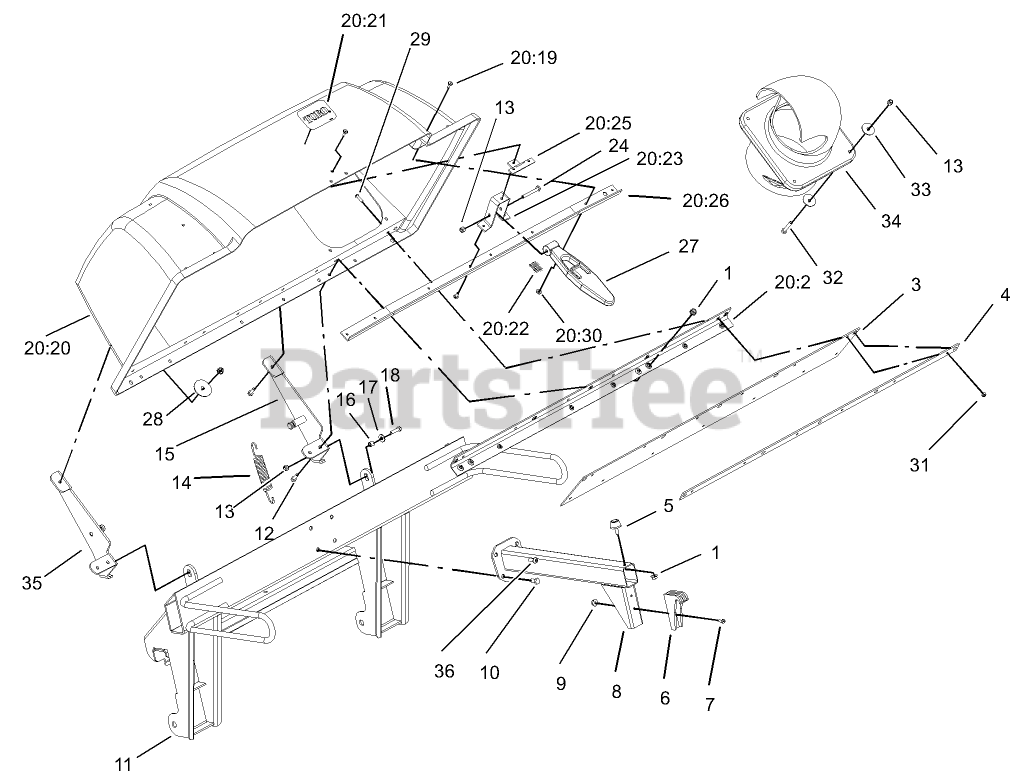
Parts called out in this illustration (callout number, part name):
1	NUT-HF
3	SEAL-HOOD
4	PLATE-BACKING
5	BUMPER
7	SCREW-PPH
8	BAG SUPPORT ASM
9	NUT-HF
10	SCREW-HH
11	Bagger-Upright
12	SCREW-HH
13	NUT-LOCK, NI
14	Spring-Extension
15	HINGE-RH
16	SPACER
17	WASHER-FLAT
18	SCREW-HH
19	RIVET-BLIND
20	Hood ASM
20:2	STIFFENER-BAGGER, TOP
20:19	RIVET-BLIND
20:20	Top-Bagger
20:21	DECAL
20:22	SCREEN-BAGGER
20:23	ANCHOR-LATCH
20:25	REINFORCEMENT-LATCH
20:26	SUPPORT-SCREEN
20:30	WASHER-FLAT
24	SCREW-HH
28	WASHER
29	SCREW-HEAD, TRUSS
31	NUT-LOCK, NI
32	SCREW-HH
33	WASHER-FLAT
34	Tube-Bagger, Upper
35	HINGE-LH
36	SCREW-HSBH
